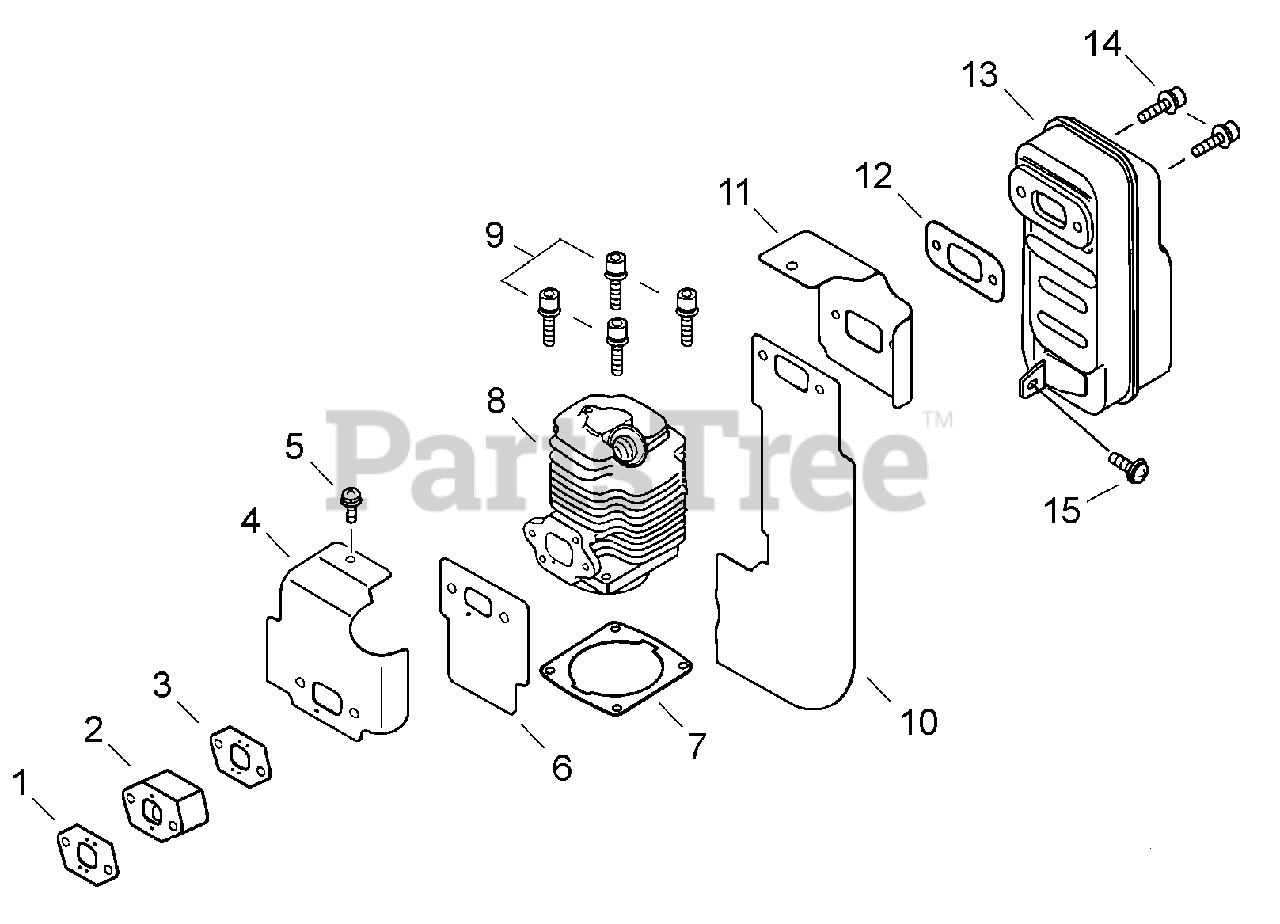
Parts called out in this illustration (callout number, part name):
1	GASKET, INTAKE
2	INSULATOR, INTAKE
3	GASKET, INTAKE
4	COVER, ENGINE - INTAKE
5	SCREW 5×10
6	GASKET, INTAKE
7	GASKET, CYLINDER
8	CYLINDER
9	BOLT 5×20
10	HEAT SHIELD, EXHAUST
11	COVER, ENGINE - EXHAUST
12	GASKET, MUFFLER
14	BOLT 6×20
15	SCREW 5×14
